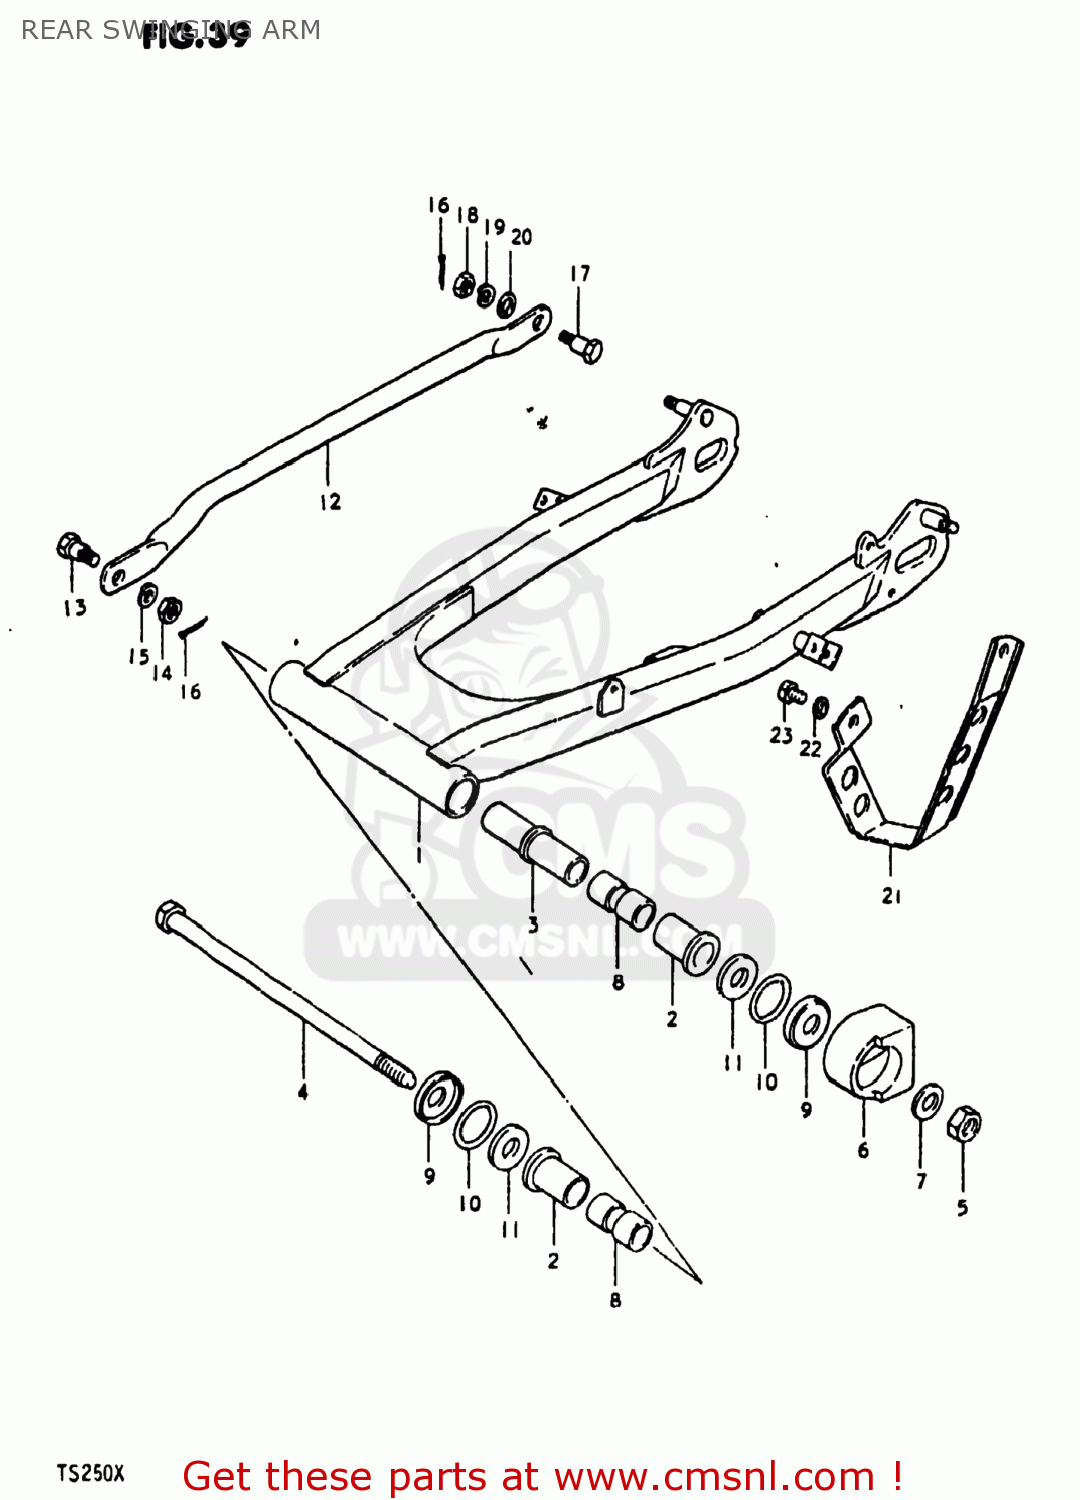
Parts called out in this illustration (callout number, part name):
1	SWING ARM ASSEMBLY,REAR
2	BUSH
3	SPACER,SWING ARM,CENTER
4	SHAFT,REAR SWING ARM
5	NUT 14MM
6	BUFFER,CHAIN TOUCH DEFLECTOR
7	WASHER
8	SPACER
9	COVER
10	O RING(D:3,ID:29.5)
11	WASHER(14.5X29X2.3)
12	TORQUE LINK,REAR
13	BOLT(8X22.5)
14	NUT
15	LOCK WASHER
16	PIN
17	BOLT(10X32.5)
18	NUT
19	LOCK WASHER
20	WASHER
21	GUIDE,CHAIN
22	LOCK WASHER
23	BOLT 8X12
